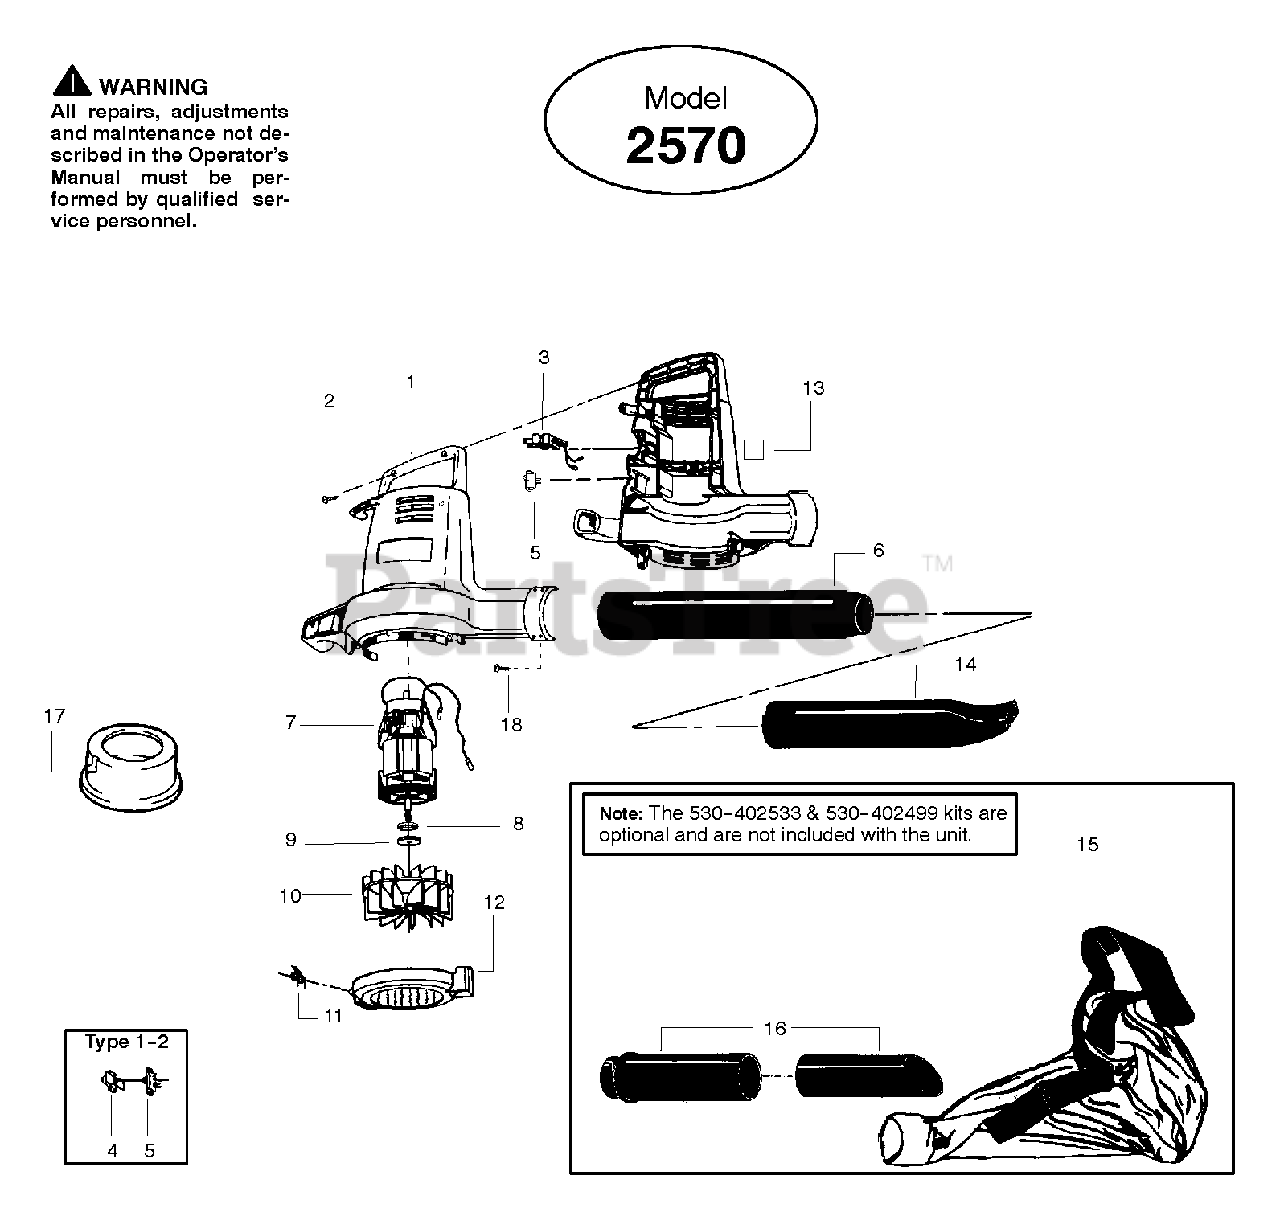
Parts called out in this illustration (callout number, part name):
1	Housing Set (Type 1,2)
1	Housing Set (Type 3)
3	Wire Harness (Type 1,2)
3	Wire Harness (Type 3)
4	Switch Cover (Type 1,2)
5	Switch (Type 1,2)
5	Switch (Type 3)
6	Blower Tube
7	Motor Ass'y. Type 1
7	Motor Ass'y. Type 2,3
8	Spacer (Type 2,3 only)
10	Impeller
12	Assy-Cover Spring
13	Pad (Type 1,2)
15	Vacuum Bag Kit
16	Vacuum Tube Kit
17	Inlet Restrictor
